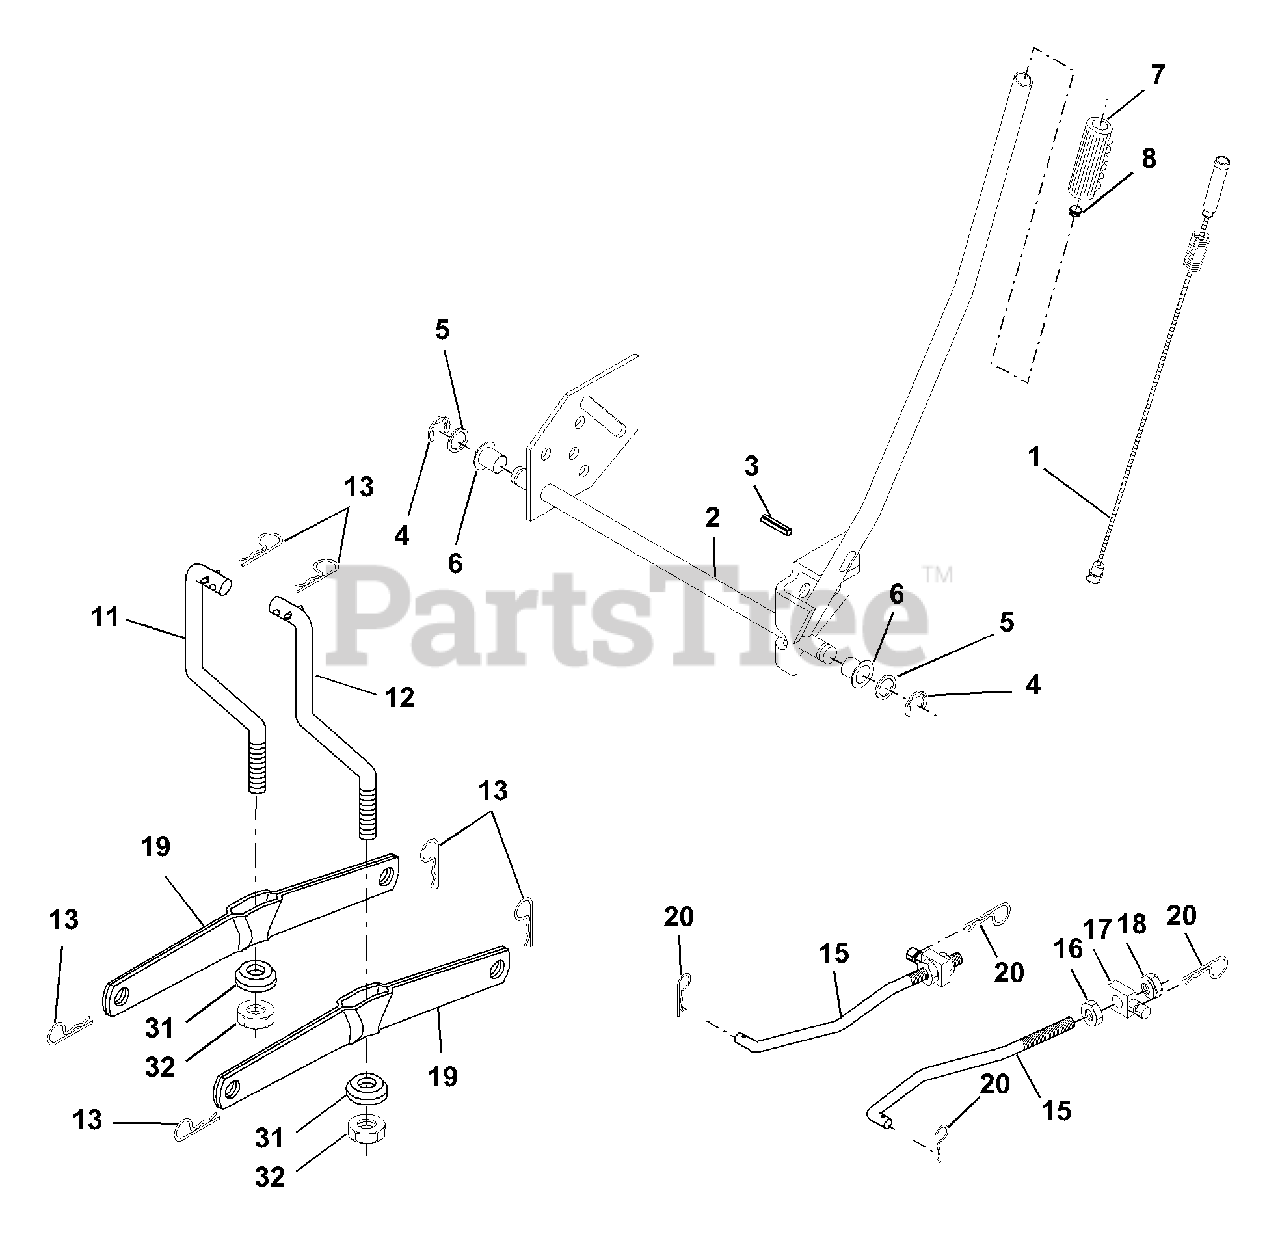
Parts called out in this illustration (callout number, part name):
1	Wire Asm Inner/Sprg W/plunger LT
2	Shaft Asm Lift
3	Pin Groove 1 500 Zinc
4	E Ring #5133-62
5	Washer Pltd 21/32 X 1 X 21ga
6	Bearing Nylon Blk 629 Id
7	Grip Handle bicycle Matte
8	Button Plunger Red
11	Link Lift LH
12	Link Lift RH
13	Retainer Spring
15	Link Front
16	Nut Jam Hex 1/2-13 Unc
17	Trunnion Blk Zinc
18	Nut Lock W/Wsh 1/2-13unc
19	Arm Suspension Rear
20	Retainer Spring Zinc
31	Bearing Pvt Lift Spherical
32	Nut Crownlock 3/8-24
